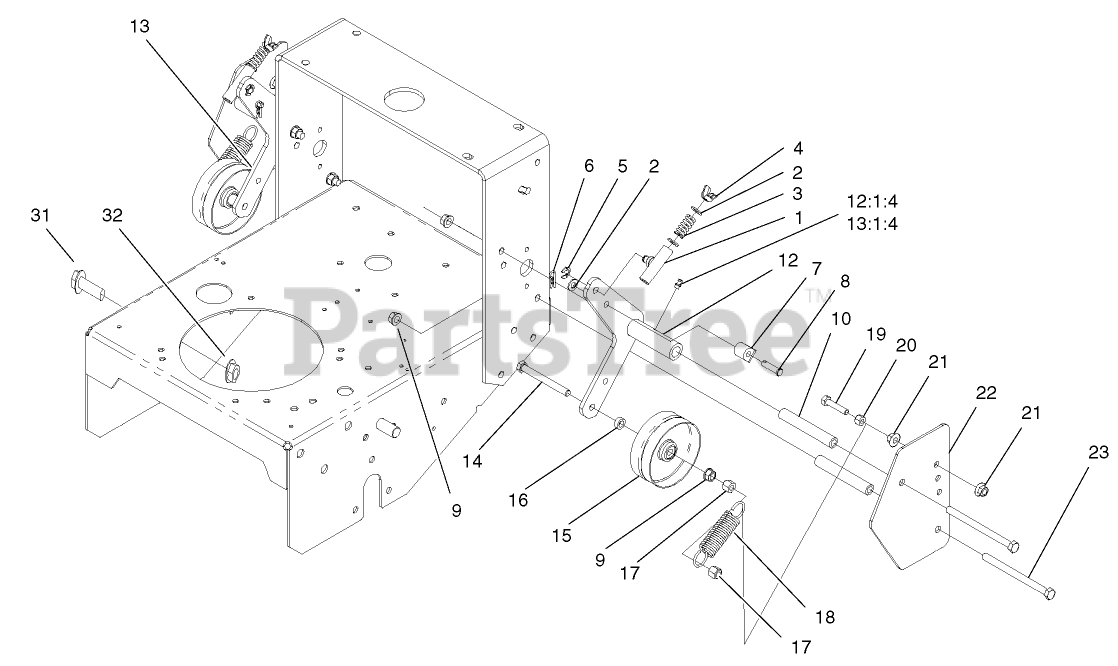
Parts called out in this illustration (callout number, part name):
1	SWIVEL-BRAKE
2	WASHER-PLAIN
3	SPRING-COMPRESSION
4	NUT-WING, LOCK
5	RING-RETAINING
6	PIN-COTTER
7	FITTING-ROD
8	PIN-CLEVIS
9	NUT-FLANGE
10	SPACER-SHIELD
11	FITTING-GREASE
12	ARM-IDLER ASM, RH
13	ARM-IDLER ASM, LH
14	Screw-HH
15	IDLER-WHEEL, DRIVE
16	Spacer-Pulley
17	NUT-LOCK, NI
18	SPRING-EXTENSION
19	SCREW-HH
20	NUT-LOCK, NI
21	NUT-HF
22	SHIELD,WHEEL DRIVE
23	SCREW-HH
24	SCREW-HHF
25	NUT-HF
